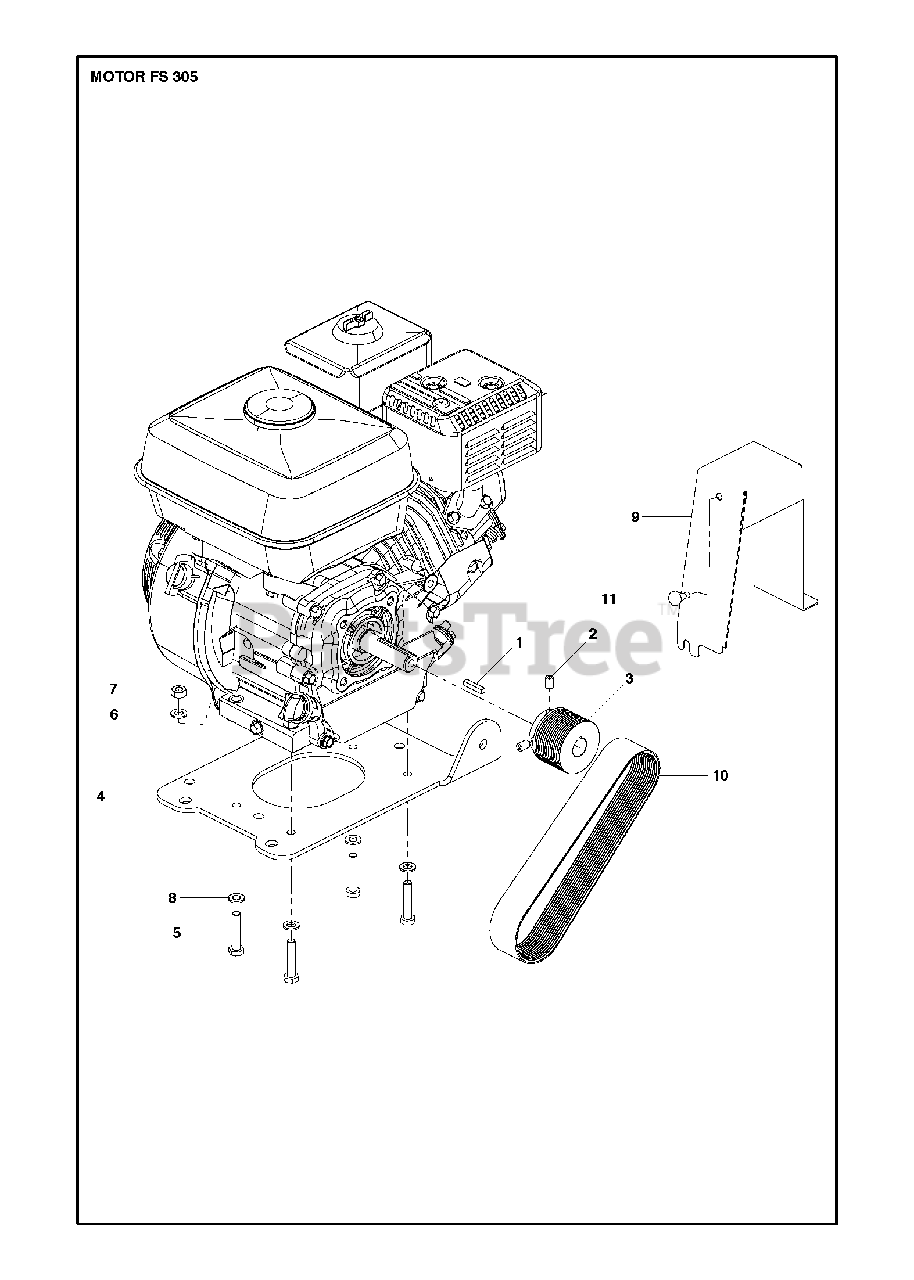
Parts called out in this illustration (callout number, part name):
6	WASHER
7	HEXAGON NUT
8	WASHER
